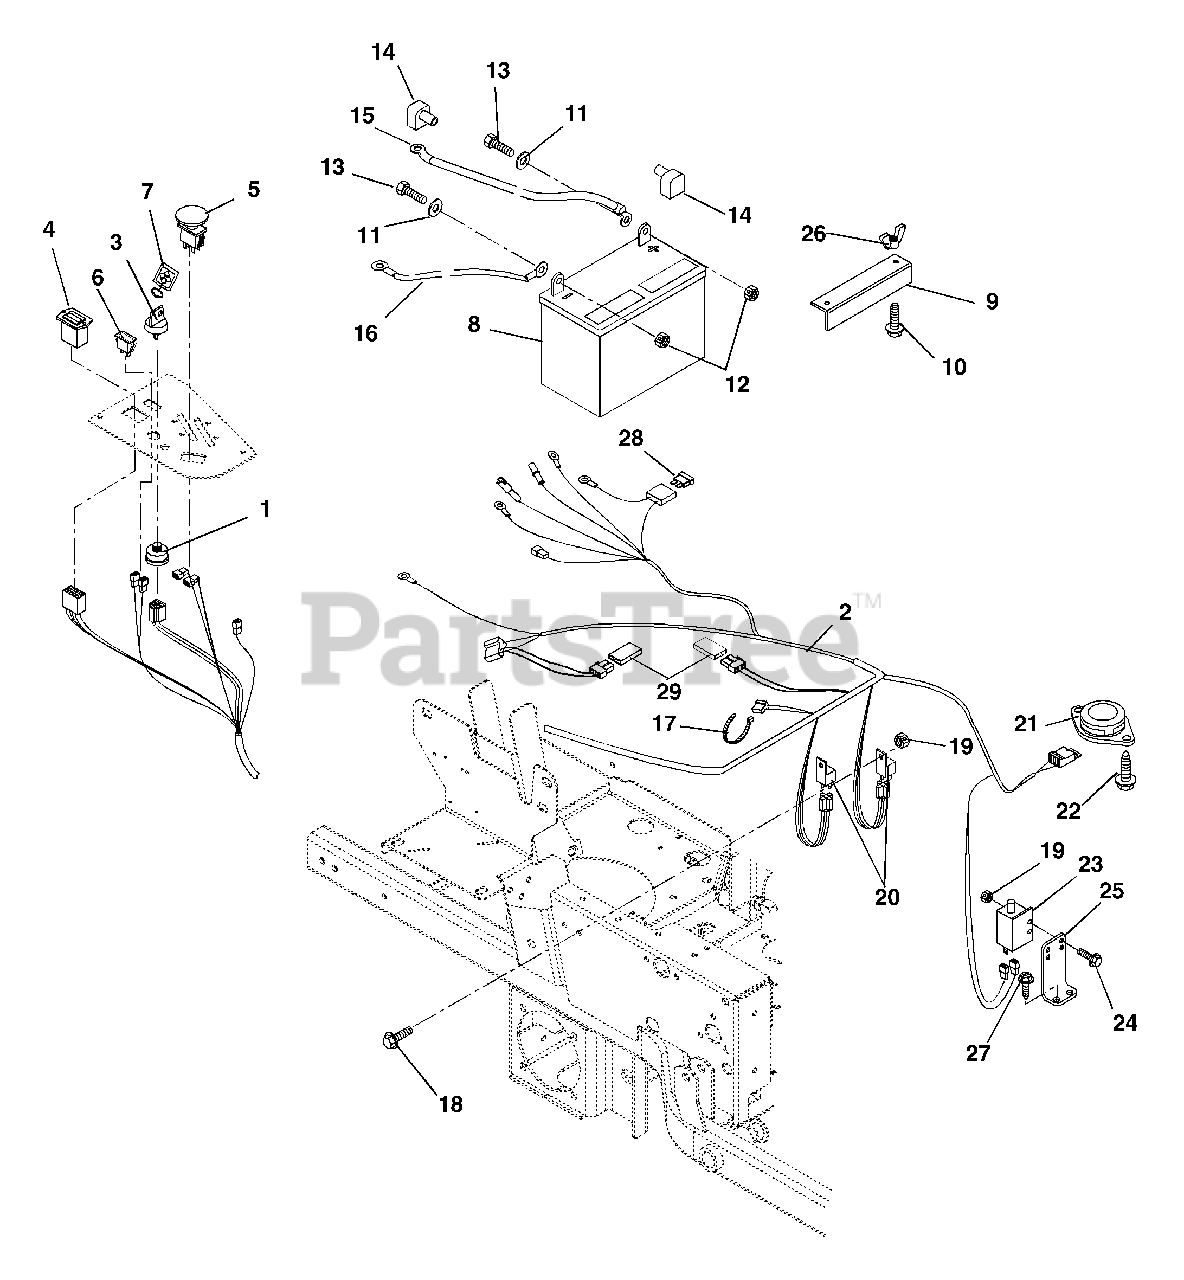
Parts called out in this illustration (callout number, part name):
1	SWITCH, IGNITION
2	HARNESS, Z- 6 PIN
3	KEY, W/ SHIELD
4	HOUR METER, QUARTZ
5	SWITCH, CLUTCH
6	LIGHT,INDICATOR
7	KEY CHAIN
8	BATTERY, 300 CCA 10U1L
9	HOLD DOWN
10	BLT-RDHDSQNK .25-20X7.50 GR2YZ
11	@WSHR-FL-STL.281X.62X.065 YWZC
12	@NUT-LK-TOP-FLG .25-20 YWZC
13	@BLT-HEX .25-20X.75 GR5 YWZC
14	INSULATOR
15	CABLE, POSITIVE BATTERY 26.00
16	CABLE, NEGATIVE BATTERY 24.00
17	CABLE TIE LG 5-1/2
18	@SCR-MCH 10-24X.50 HWH YWZC
19	@NUT-LK-NYL 10-24 W/INSRT YWZC
20	RELAY
21	SEAT SWITCH
22	@SCR-TAP 12-24X.50 HWH TR YWZC
23	SWITCH- SINGLE POLE N.O.
24	@SCR-MCH 10-24X.75 HWH YWZC
25	BRAKE SWITCH MOUNT - BLACK
26	NUT-LK WING .250-20 YWZC
27	@SCR-TAP .25-20X.50 HWH TR YWZ
28	FUSE, 30 AMP.
29	DIODE, CONNECTOR SHELL
